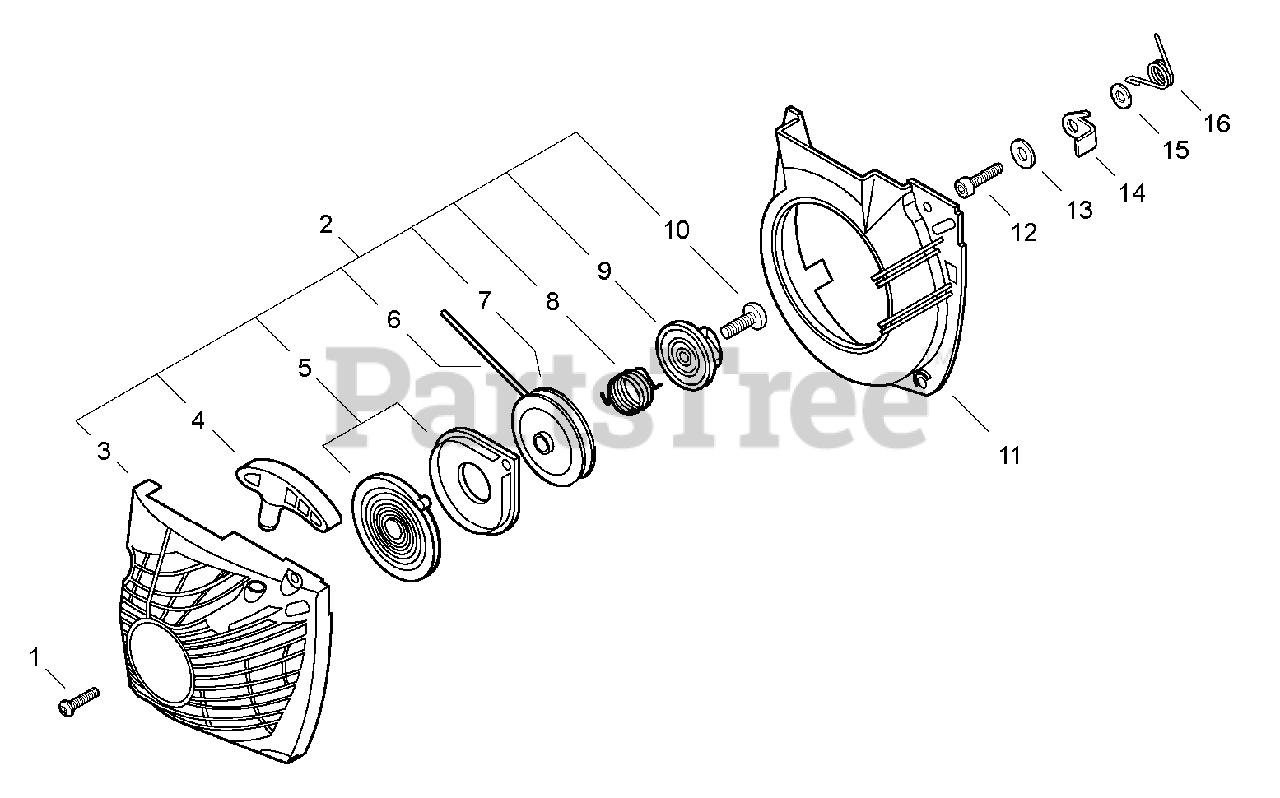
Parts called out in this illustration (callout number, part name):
1	SCREW - 5X20 -- TAPPING
2	STARTER ASSY
3	CASE, STARTER
4	GRIP, STARTER
5	REWIND SPRING ASSY
6	ROPE, STARTER 3.5×900
7	REEL, ROPE
9	CATCHER, PAWL
10	SCREW
11	COVER, FAN
12	SCREW - 5X14
13	WASHER - 5
14	PAWL, STARTER
16	SPRING, RETURN
